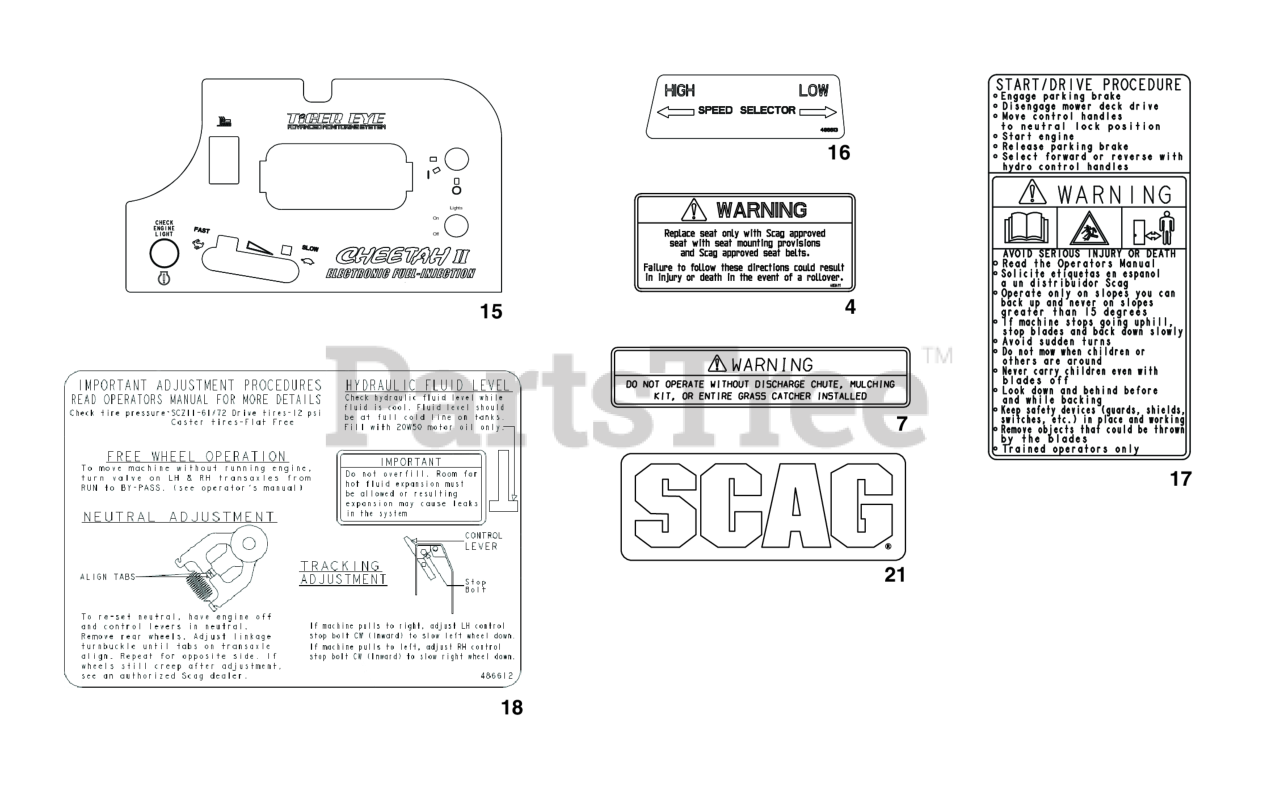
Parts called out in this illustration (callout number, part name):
4	Decal, Seat Replacement
7	Decal, Warning-Discharge
15	Decal, Instrument Panel - SCZII - EFI
16	Decal, Speed Control
17	Decal, Start / Drive
18	Decal, Adjustments - SCZII
21	Decal, Scag - Fuel Tank
